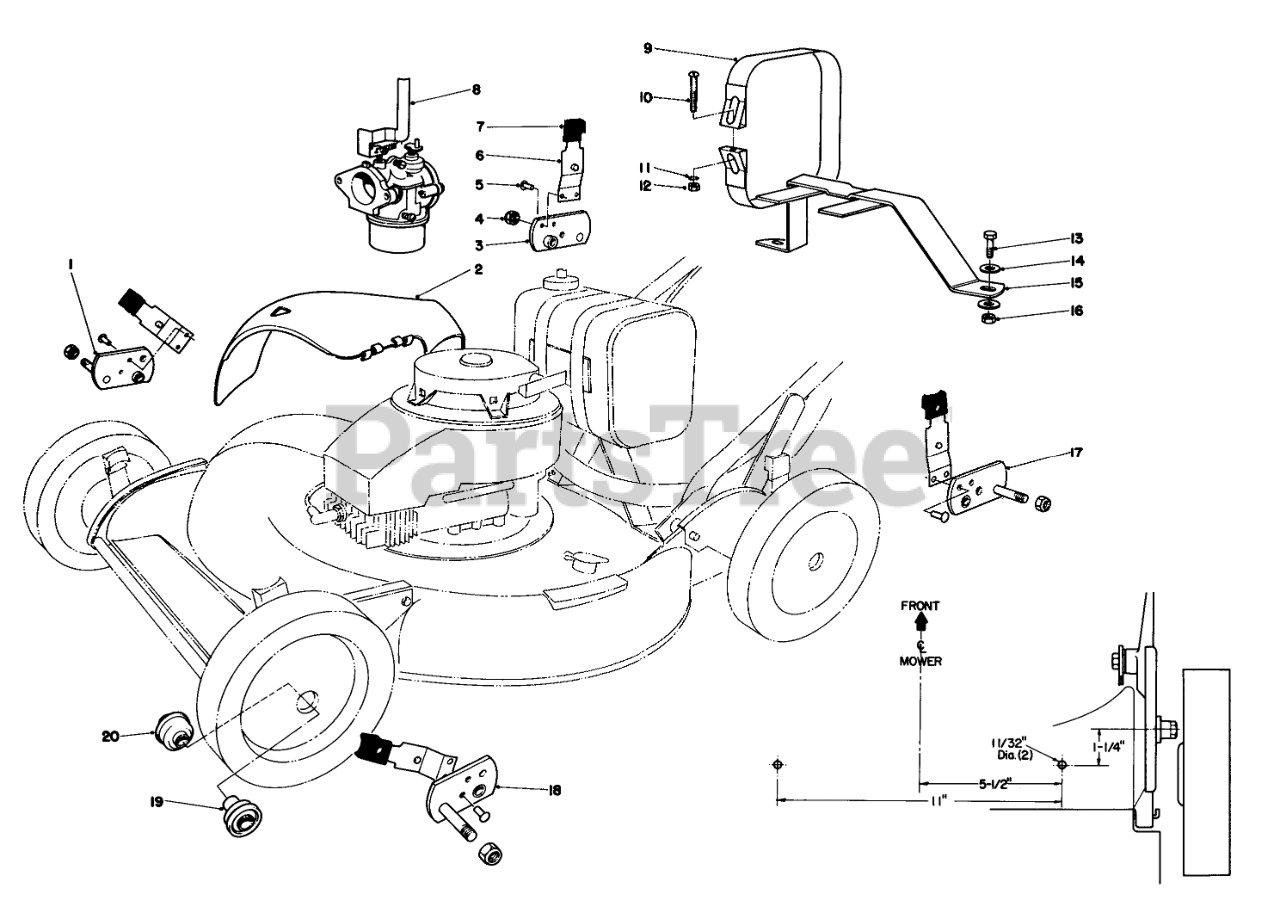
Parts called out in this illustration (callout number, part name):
1	PIVOT ARM WA A
2	Deflector
3	PIVOT ARM WA D
4	NUT-LOCK, NI
5	Rivet
6	Spring Arm
7	KNOB-ARM
8	Carburetor (Furnished by Tecumseh)
9	TANK STRAP WA
10	1/4-20 X 2 FIL HD MS
11	WASHER-LOCK
12	NUT-HEX
13	Screw
14	WASHER-PLAIN
15	Tank Bracket
16	NUT-LOCK, CONE
17	Pivot Arm "B"
18	Pivot Arm "C"
19	BEARING
20	BEARING
